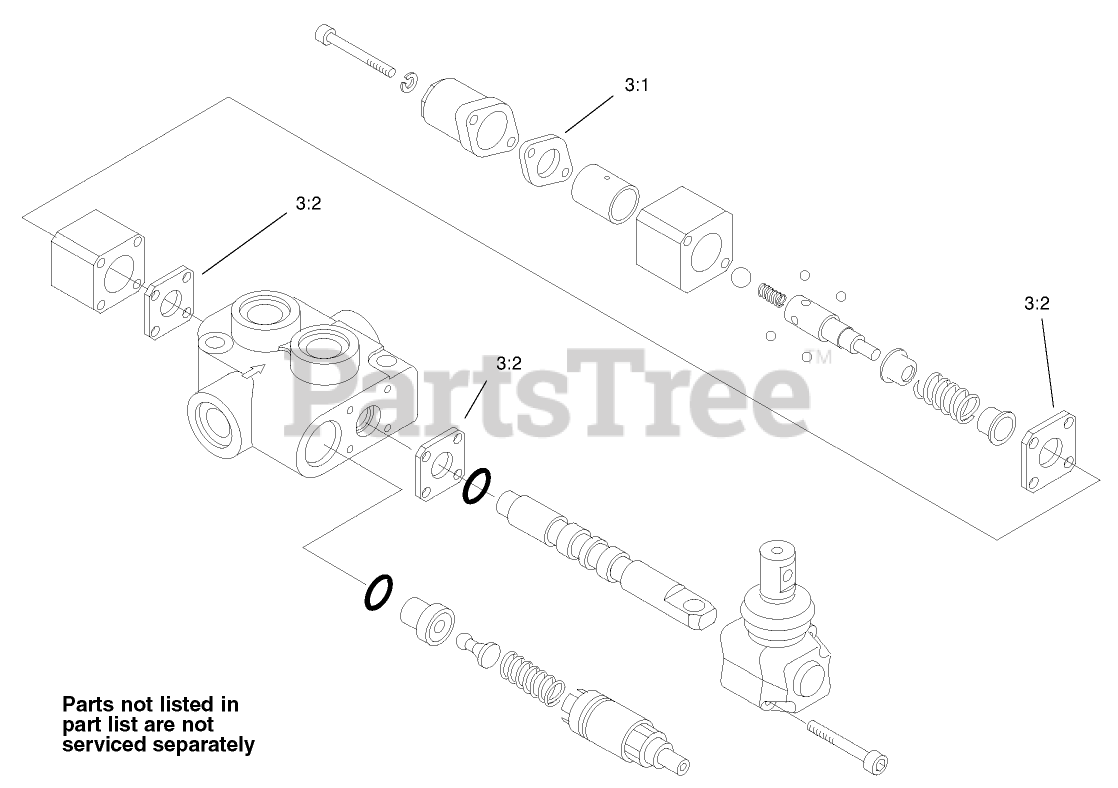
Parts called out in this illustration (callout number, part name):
3	SEAL KIT
3:1	GASKET
3:2	GASKET
